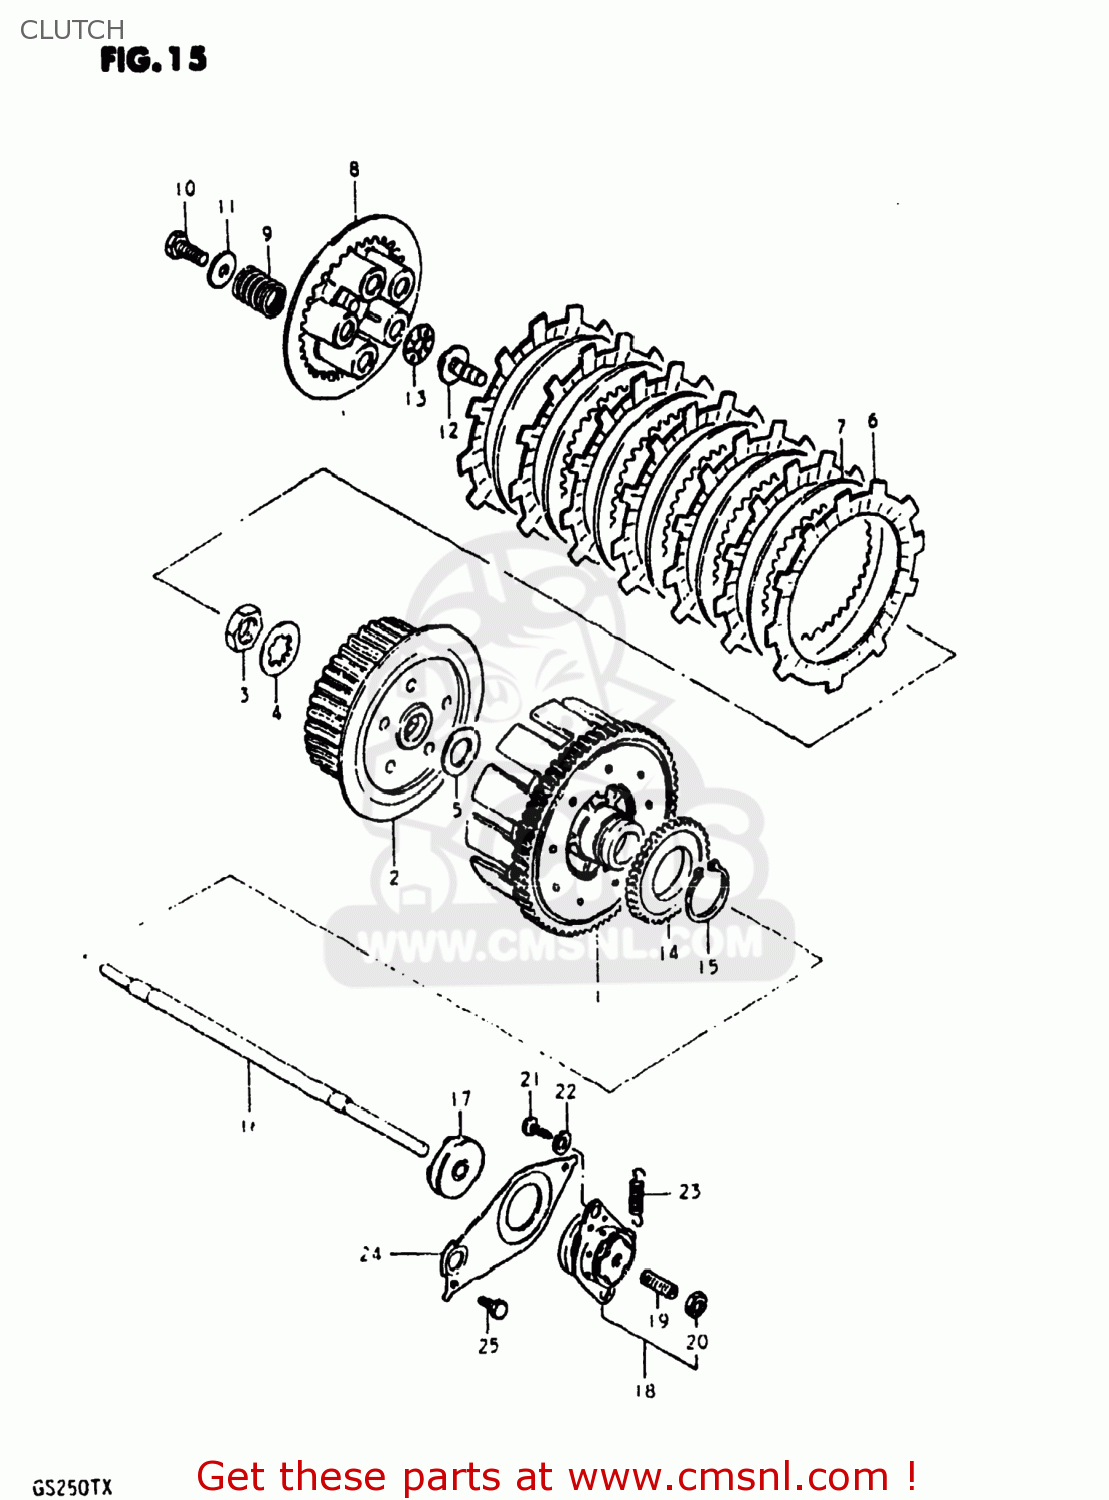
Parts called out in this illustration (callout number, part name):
1	GEAR ASSEMBLY,PRIMARY DRIVE
2	HUB,CLUTCH SLEEVE
3	NUT
4	WASHER
5	WASHER
6	PLATE,CLUTCH DRIVE
7	PLATE,CLUTCH DRIVEN (NAS)
8	DISC,CLUTCH PRESSURE
9	SPRING
10	BOLT(5X16)
11	WASHER (5.5X16X1.2)
12	ROD,CLUTCH RELEASE
13	BEARING(10X22X2.8)
14	GEAR,OIL PUMP DRIVE
15	CIRCLIP
16	ROD,CLUTCH PUSH
17	SEAL,OIL(6X31X10)
18	SCREW ASSEMBLY,CLUTCH RELEASE
19	SCREW
20	NUT 6MM
21	SCREW
22	WASHER
23	SPRING
24	PLATE,CLUTCH PUSH ROD
25	BOLT
